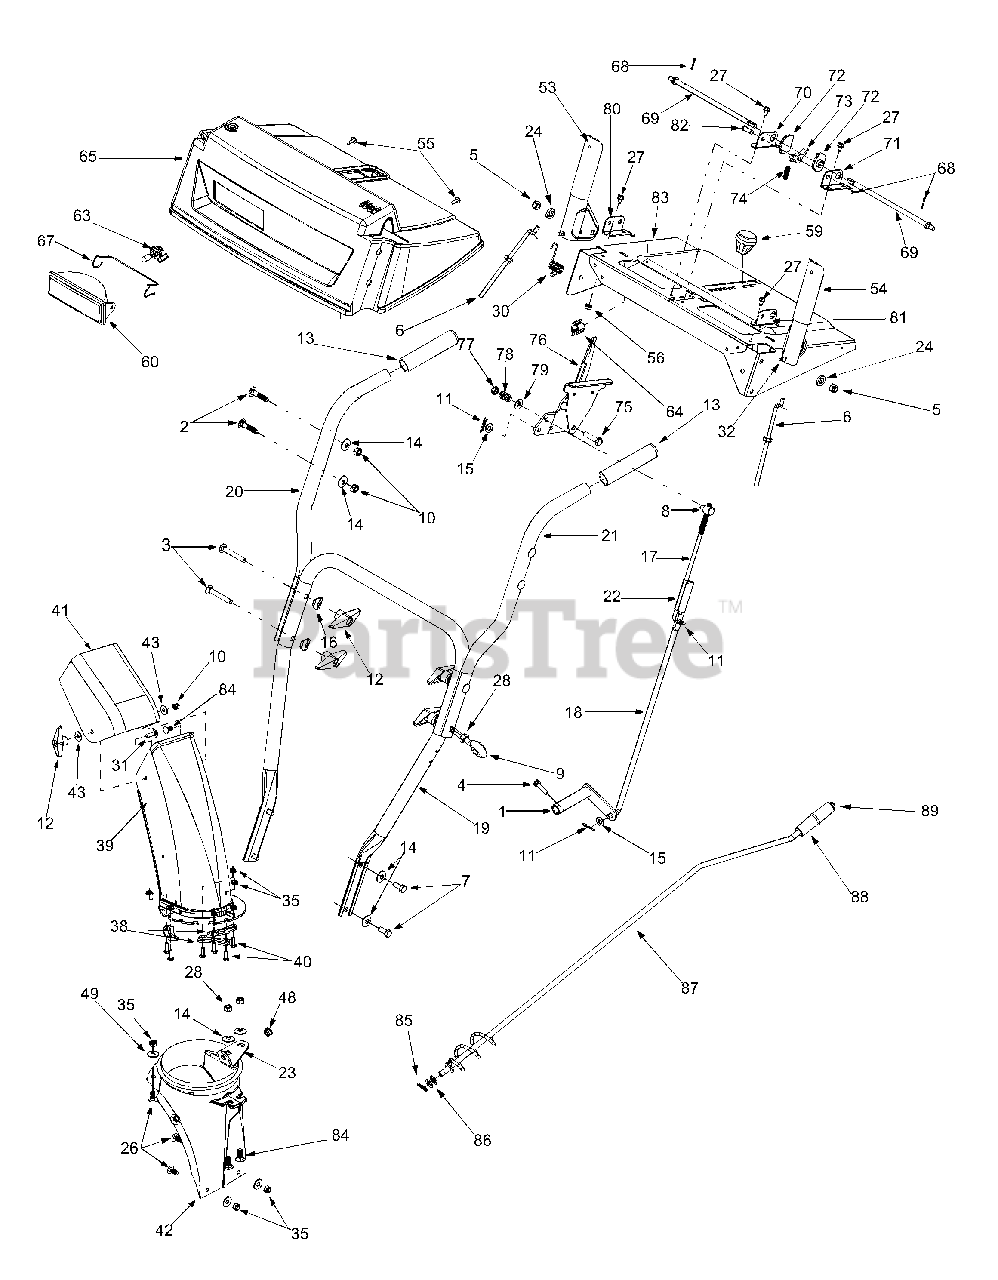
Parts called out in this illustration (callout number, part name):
2	Carriage Bolt 5/16-18 x 1.75"
3	Carriage Bolt 5/16-18 x 2.25"
4	Self-tapping Screw 1/4-20 x 1"
5	Hex Lock Nut 5/16-18
6	Z Fitting
7	Hex Screw 5/16-18 x .75"
8	Ferrule
9	Eyebolt
10	Hex Nut 5/16-18
11	Cotter Pin
12	Handle Knob
14	Belleville Washer
15	Flat Washer
16	Saddle Washer
17	Shift Rod, Upper
18	Shift Rod, Lower
24	Washer .72 OD x .135 ID
25	Carriage Bolt, 5/16-18 x 1.5"
26	Carriage Bolt, 1/4-20 x .750"
27	Self-tapping Screw, 1/4-20 x 0.5"
28	Hex Nut 5/16-18
30	Torsion Spring
31	Carriage Screw 5/16-18 x 1.0
32	Rubber Bumper
35	Hex Flange Lock Nut
38	Chute Flange Keeper
39	Lower Chute
40	Hex Cap Screw 1/4-20 x .75
41	Upper Chute
42	Chute Adapter, 5"
43	5/16 Washer
47	Control Cable
48	Plastic Bushing
49	5/16 Washer
53	Handle Assembly RH
54	Handle Assembly LH
55	Special Hex Screw
56	Hex Sems Nut, 1/4-20
57	Hex Nut
59	Shift Knob
60	Lamp Housing
63	Halogen Lamp, 50W, 12V
64	Mounting Clamp
65	Handle Panel
67	Headlight Retainer
68	Cotter Pin, 3/32 x .75
69	Cam Rod
72	Cam Handle Lock
73	Handle Lock Pawl
74	Compression Spring, .36 x 1.0
75	Hex Cap Screw, 3/8-24 x 1.5
78	Comp. Spring, .39 x .6 x .88
79	Bell Washer
82	Clevis Pin
85	Hairpin Clip
86	Flat Washer
87	Chute Crank
88	Chute Crank Knob
89	Push Cap
